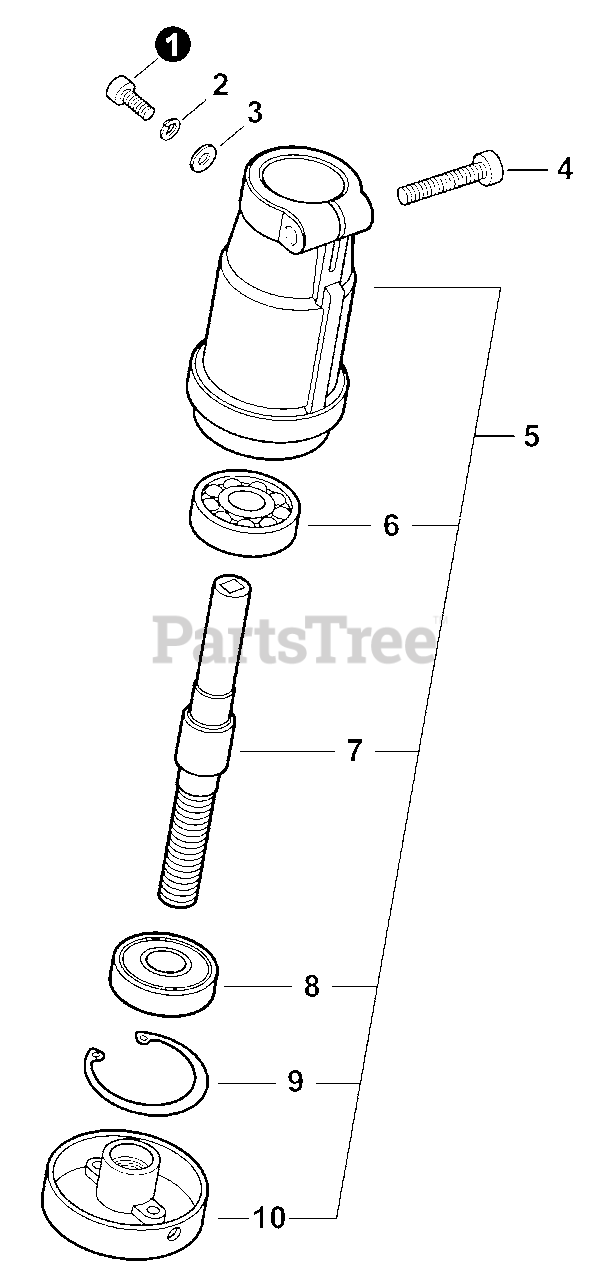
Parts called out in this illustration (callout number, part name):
1	BOLT, TORX 4×10
2	WASHER, SPRING 4mm
3	WASHER 4MM
4	BOLT, TORX 5×25
5	GEAR CASE ASSY
6	BEARING, BALL 6200
7	SHAFT, GEAR
8	BEARING, BALL 6200
9	E-RING 30
10	PLATE, ADAPTOR - UPPER
